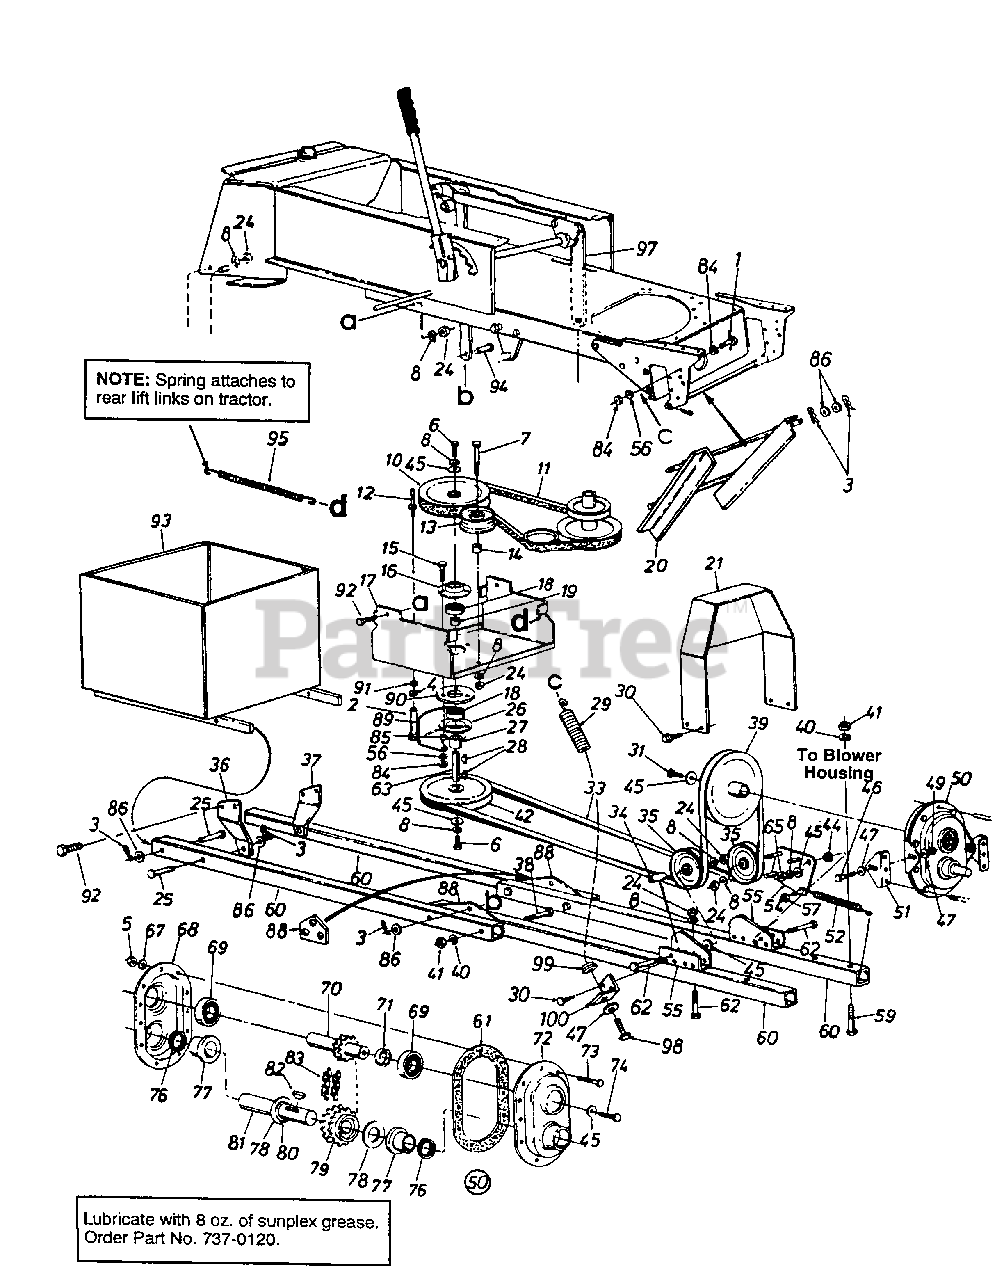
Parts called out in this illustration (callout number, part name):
1	Hex Bolt 5/16-24 x 2" Lg.
2	Clevis Pin Spec. 3/8" Dia. x 2.62" Lg.
3	Intern. Cot. Pin
4	L-Wash. 1/4" I.D.
5	Hex Nut 1/4-28 Thd.
6	Hex L-Scr. 3/8-24 x 1.0" Lg.
7	Hex Bolt 3/8-16 x 2.25" Lg.
8	L-Wash. 3/8" I.D.
10	5/8" "V"-Pulley.79" I.D. x .65" O.D.
11	"V"-Belt
12	Belt Guard Pin
13	Fl-Idler 3.75" O.D.
14	Spacer .385" I.D. x .63" O.D. x .76"
15	Hex Bolt 5/16-24 x 1.50
16	Open Brg. Hsg.
19	Spacer .8" I.D. x 1" O.D.
20	Guide Brkt. Ass'y.
21	Belt Cover Ass'y.
24	Hex Nut 3/8-16 Thd.
25	Clevis Pin .50" Dia. x 1.75" Lg.
26	Brg. Hsg. Ass'y.
27	Spacer .8" I.D. x 1" O.D. x .125"
28	Woodruff Key 3/16" x 5/8" HT
29	Helper Spring
30	Hex Wash. HD-Tap Scr. 5/16-18 x .50
31	Hex L-Scr. 3/8-24 x 1.0" Lg.
33	"V"-Belt
34	Spacer .39" I.D. x .62" O.D. x 1.74" Lg.
35	V-Idler Pulley
39	5/8" "V"-Pulley 7.5" O.D.
40	L-Wash. 1/2" I.D.
41	Hex Nut 1/2-13 Thd.
42	5/8" "V"-Pulley
44	Shld. Spacer
45	Fl-Wash. .4" I.D. x 1.25" O.D. x .16"
46	Hex Bolt 5/16-18 x 1.25" Lg.
47	Bell-Wash. .345" I.D. x .88" O.D. x .06"
49	Hex Nut 5/16-18 Thd.
50	Comp. Chain Gear Box Ass'y.
51	Gear Box Support Brkt.
52	Ext. Spring .6" Lg.
56	L-Wash. 5/16" I.D.
57	Hex Nut 3/8-24 Thd.
59	Hex Bolt 1/2-13 x 3" Lg.
60	Sq. Tubing 43" Lg.
61	Gasket
62	Hex Bolt 3/8-16 x 3" Lg.
63	Shaft - .787" Dia. x 3.81" Lg.
65	Hex L-Nut 3/8-16 Thd.
67	Wave Spring Wash. .27" I.D. x .51" O.D. x .03"
68	Complete Gear Hsg. Half - L.H.
69	Ball Brg. 1" I.D. x 2" O.D.
70	11-2 x .5 Pitch Sprocket Shaft Ass'y.
71	Spacer 1 I.D. x 1.18" O.D. x .44"
72	Comp. Gear Hsg. Half - R.H.
73	Hex Bolt 1/4-28 x 1" Lg.
74	Hex L-Scr. 3/8-24 x 1" Lg.
76	Oil Seal 1.25" I.D.
77	Flange Brg. 1.25" I.D.
78	Fl-Wash. 1.25" I.D. x 2" O.D. x .036"
79	DBL Sprocket 19-2 Teeth x .5" pitch
80	Snap Ring for 1.25" Dia. Shaft
81	Gear Shaft 1.25 Dia. x 6" Lg.
82	Hi-Pro Key 1/4" x 7/8"
83	40-2 Chain 1/2" Pitch x 25 Links
84	Hex Nut 5/16-24 Thd.
85	Spacer .380" I.D. x .625" O.D. x .227
86	Fl-Wash. .53" I.D. x 1" O.D. x .06"
88	Attaching Plate (46" Decks)
91	Hex L-Nut 1/4-20 Thd.
92	Hex Bolt 3/16 x 1" Lg.
93	Weight Box Ass'y.
95	Extension Spring
97	Deck Lift Link Ass'y.
98	Hex Bolt 5/16-18 x 1.5" Lg.
99	Spring Insert
